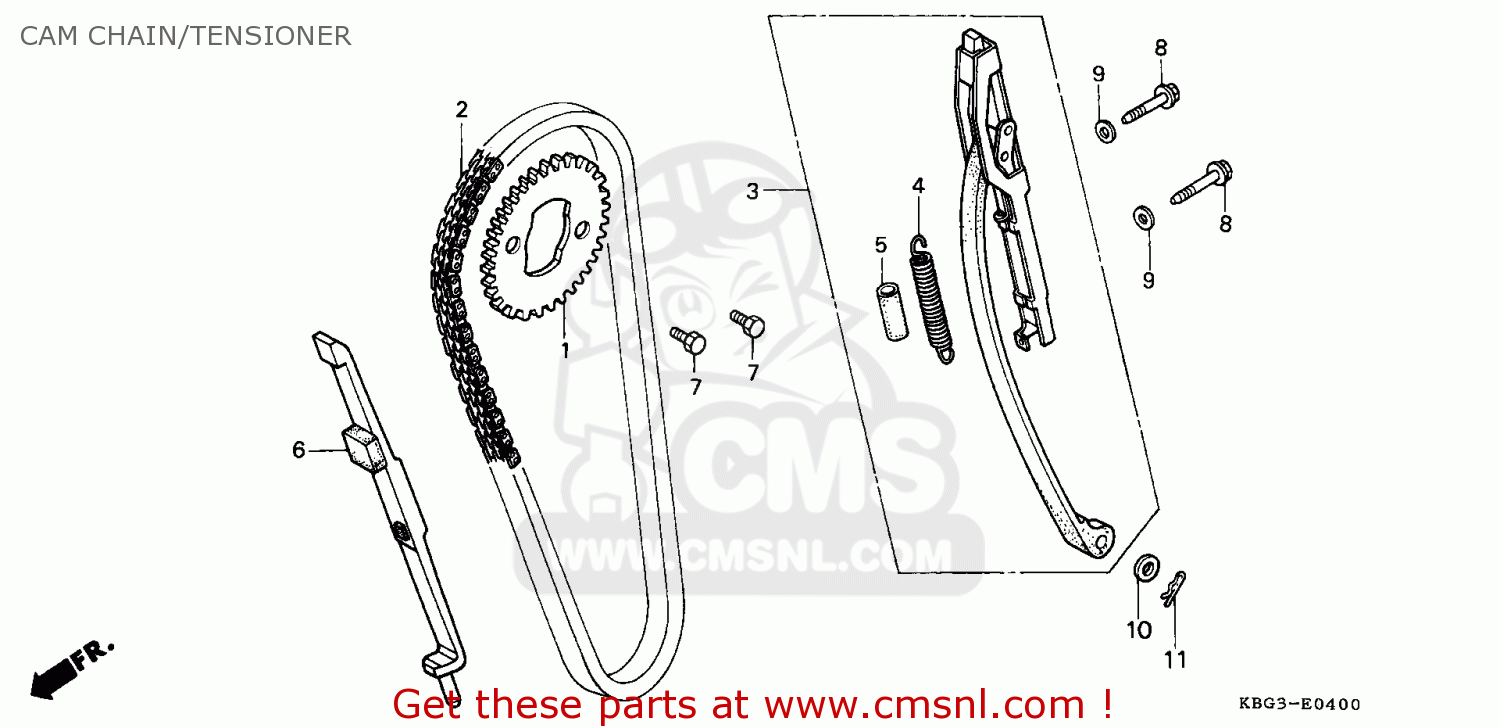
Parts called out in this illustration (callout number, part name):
1	SPROCKET,CAM (38T
2	CHAIN CAM
3	TENSIONER,CHAIN
4	SPG,TENSIONER
5	TUBE,TENSION SPG
6	GUIDE,CAM CHAIN
7	BOLT,KNOCK,7X12
8	BOLT,SPECIAL 6MM
9	WASHER SEAL, 6MM
10	WASHER A,TACH.
11	PIN,LOCK 6MM
